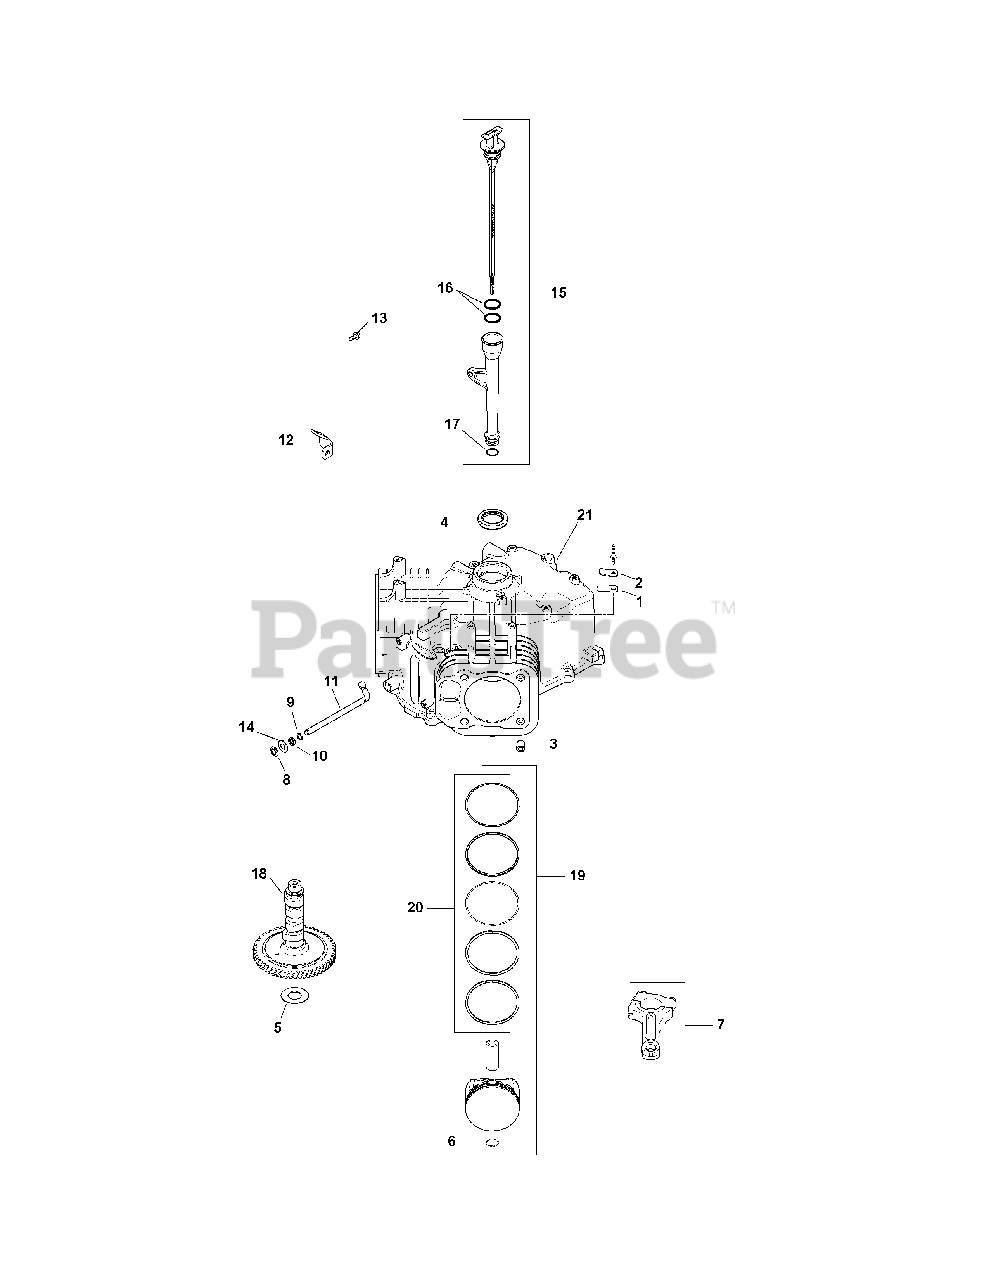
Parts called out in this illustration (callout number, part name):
1	Breather Reed
2	Breather Reed Retainer
4	Oil Seal, 1.78 x 1.26
5	Camshaft Shim, .028 (White)
5	Camshaft Shim, .03 (Blue)
5	Camshaft Shim, .032 (Red)
5	Camshaft Shim, .034 (Yellow)
5	Camshaft Shim, .036 (Green)
5	Camshaft Shim, .038 (Gray)
5	Camshaft Shim, .04 (Black)
6	Piston Pin Retainer
7	Connecting Rod (STD)
8	Ring Retainer
9	Flat Washer, 11/32
10	Governor Cross Shaft Seal
11	Governor Cross Shaft
12	Oil Fill Tube Bracket
13	Flange Screw, M5 x .8 x 13
14	Flat Washer, 9mm
15	Dipstick & Tube Kit
17	Lower Oil Fill Tube O-Ring
18	Camshaft Assembly
19	Piston Kit w/ Ring
19	Piston Kit w/ Ring (0.25) 83mm
19	Piston Kit w/ Ring (0.08) 83mm
20	Ring Set, Piston STD
20	Ring Set, Piston (.08)
20	Ring Set, Piston (.25)
21	Crankcase (Use Short Block)
